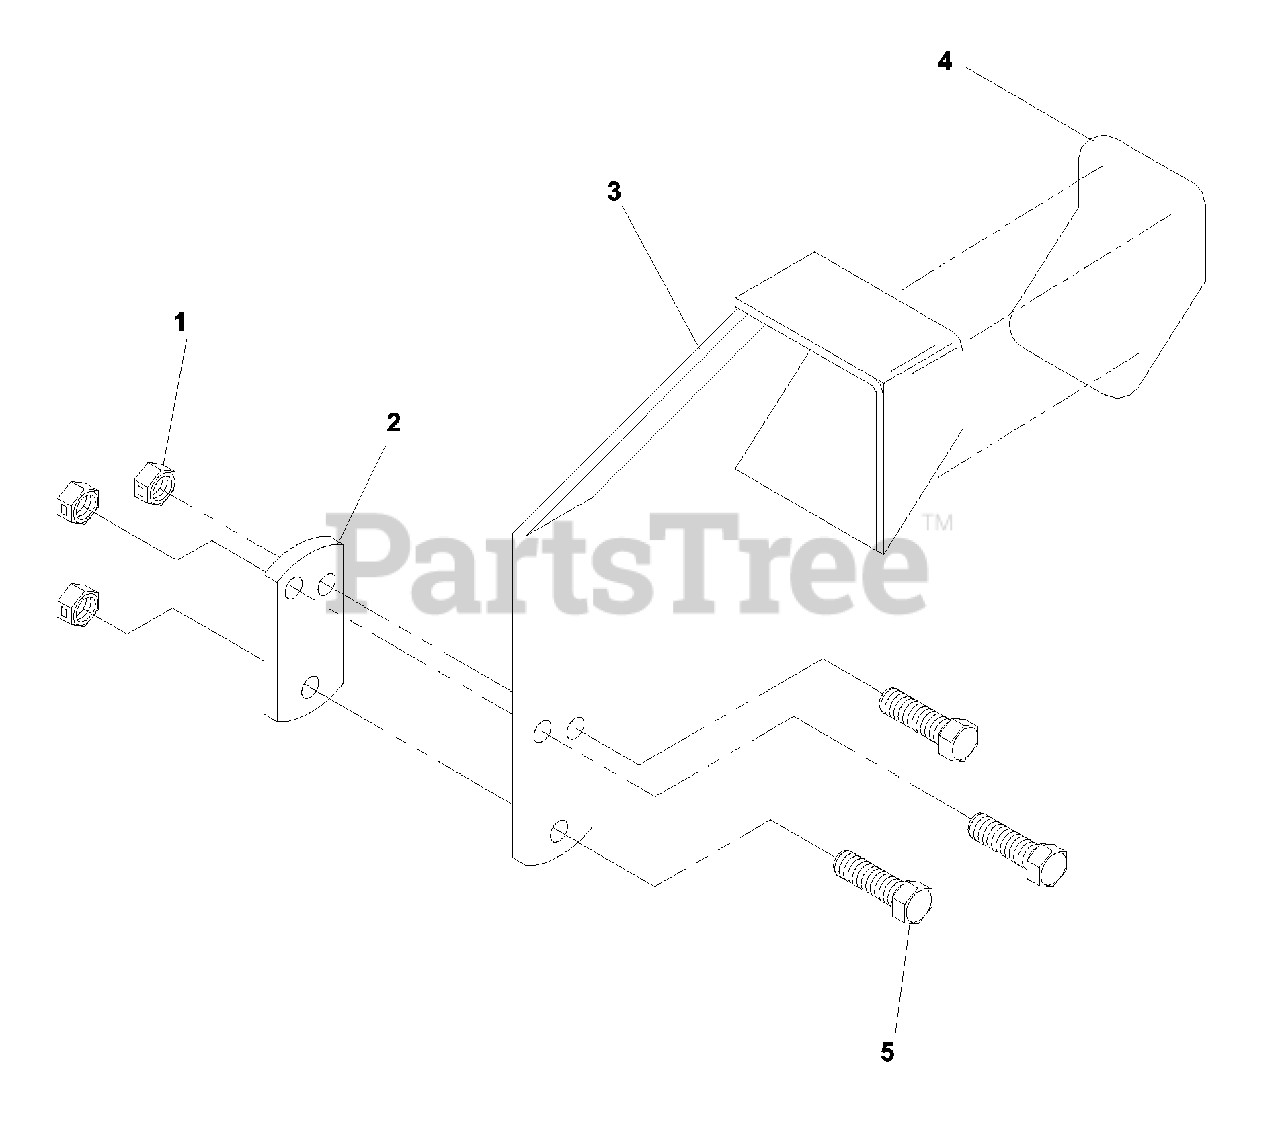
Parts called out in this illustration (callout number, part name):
1	Nut, 3/8-16, nyloc
2	Plate, tighting
3	Pedal, lift
4	Pad, anti-skid
5	Bolt 3/8-16 x 1 1/2
